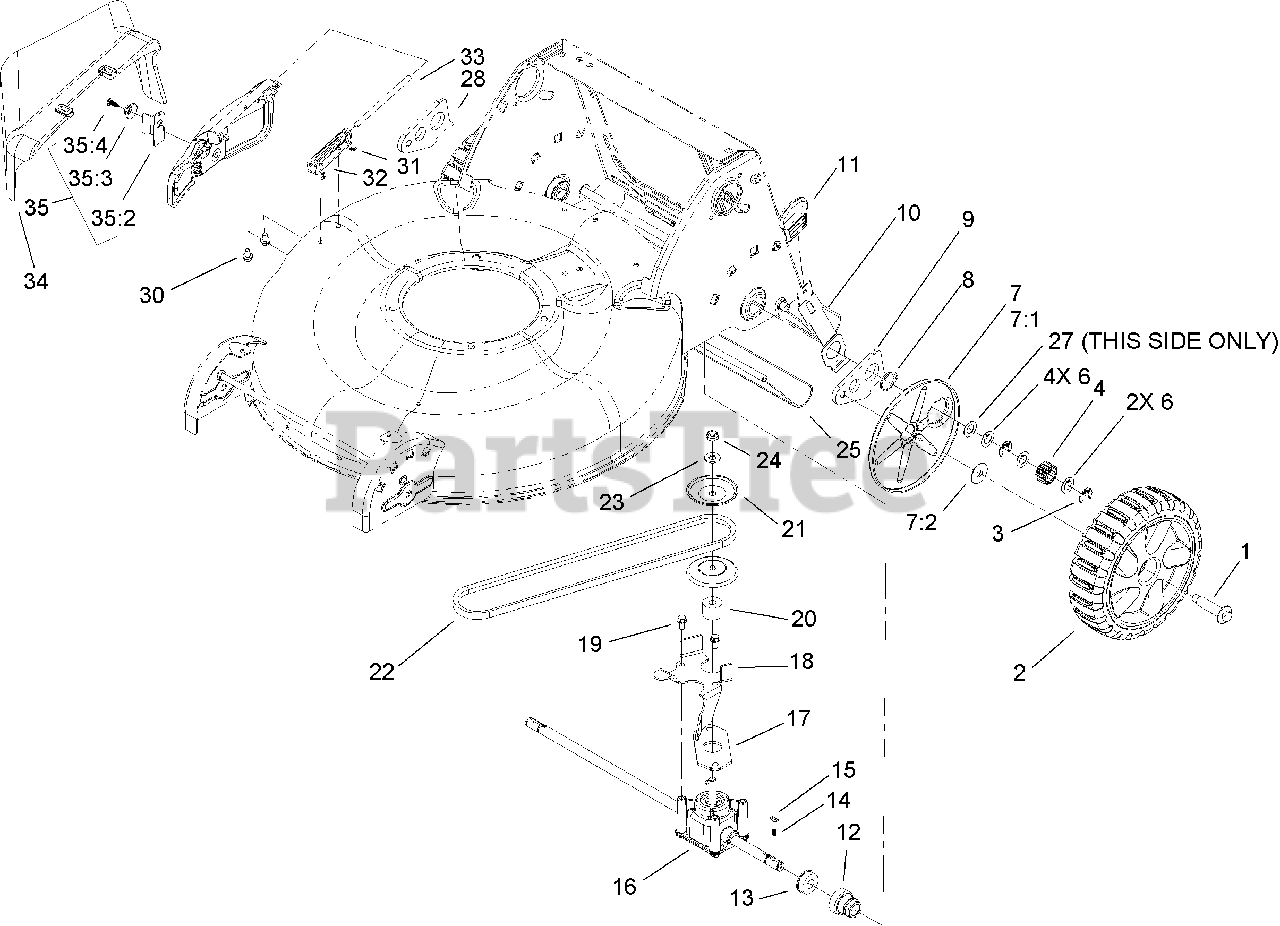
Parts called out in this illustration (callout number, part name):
1	BOLT-SHOULDER
2	REAR WHEEL ASM
3	KLIPRING-LOCKING
4	Gear-Pinion, 15t
6	Washer-Thrust
7	WHEEL COVER ASM
7:1	COVER-WHEEL
7:2	WASHER-STEPPED
8	RING-RETAINING
9	ARM-REAR PIVOT, LH
10	ARM-SPRING, REAR
11	KNOB-LEVER, HOC
12	RETAINER-BEARING, HOC
13	BEARING-BALL
14	SPRING-COMPRESSION
16	TRANSMISSION ASM
17	GASKET-GEARBOX
18	BRACKET-TRANSMISSION
19	SCREW-HWH
21	PULLEY-HALF
23	WASHER-FLAT
24	NUT-LOCK
25	SHIELD-TRAILING
28	ARM-REAR PIVOT, RH
30	SCREW-HWH
31	SPRING-TORSION
32	BRACKET-COVER
33	ROD-COVER
34	CHUTE-DISCHARGE, SIDE
35	DISCHARGE DOOR ASM
35:2	LATCH-DOOR
35:3	CAP-DOOR
35:4	SCREW-PLASTITE
